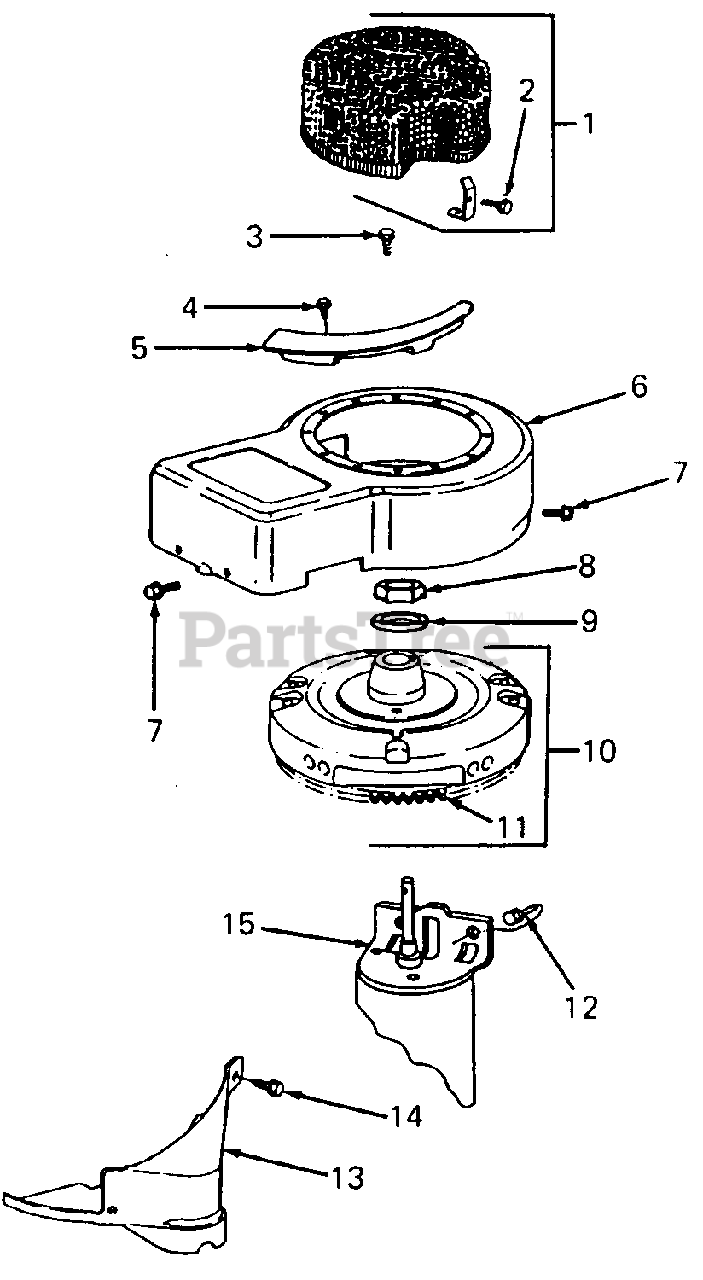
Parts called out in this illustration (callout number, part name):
1	Guard, Debris
2	Screw, Hex Washer Head
3	Screw, Hex Head Sem
4	Screw, Hex Head
5	Guard, Flywheel
6	Housing, Blower
7	Screw, Blower Housing Mtg Sem
8	Nut, Hex
9	Washer, Spring
10	Flywheel & Ring Gear Assy, Magneto
11	Gear, Ring
12	Screw, Sem Starter Mtg
13	Cover, Starter
14	Screw, Sem
15	See Starter Motor
